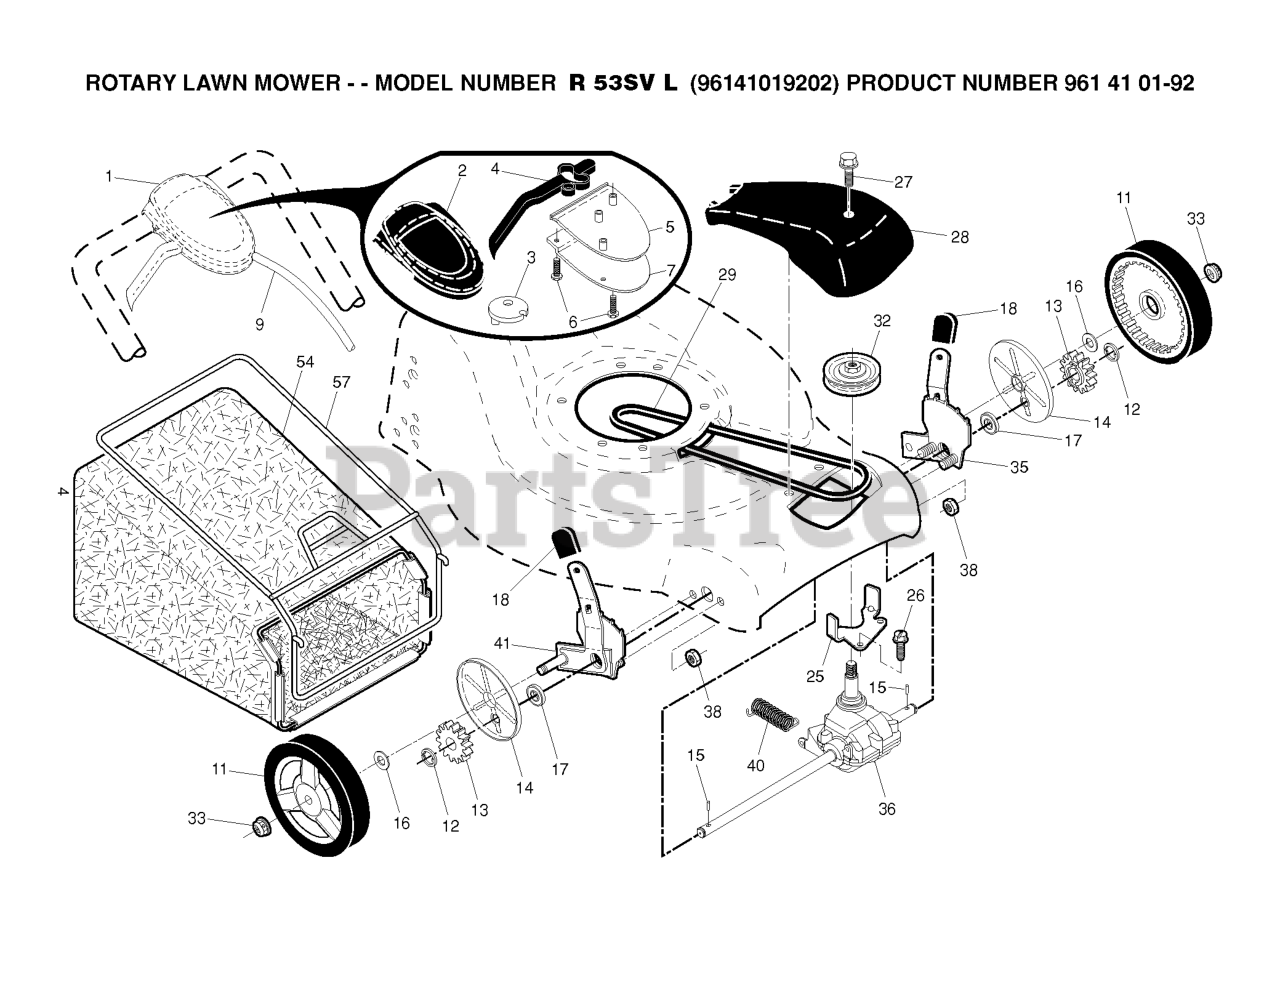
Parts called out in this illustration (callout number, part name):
1	CONTROL.DR.QW.21FGD.BS.GY/BLK
2	COVER TOP AUTO WALK CONTROL
3	PULLEY.CAM.DRIVE.CONTROL.EZ
4	LEVER
5	COVER BOTTOM AUTO WLK CONTROL
6	SCREW, PHILLIPS HEAD 10 X 5/8
7	BRACKET.DRIVE.CONTROL.MOUNT.BL
9	CABLE ASSEMBLY, DRIVE
11	WHEEL.8X1.75.H3SPK.RAD3.GY.BU3
12	E-RING 7/16 RE
13	PINION.14.TEETH.FGD
14	COVER.DUST.WHEEL
15	PAWL, DRIVE
16	WASHER FLUT
17	BEARING
18	SELECTOR KNOB
25	BELT KEEPER
27	SCREW, HEX HD TAPPING #10-24 1
28	COVER.DRIVE.21.FWGD.GRAY
29	BELT.DRIVE.FG
32	RP PULLEY.DRIVE.EZ
33	NUT.HEX.FLANGE.3/8-16.LO(3 2)
35	RP KIT, WHEEL ADJUSTER, LH
36	TRANSMISSION.21.FGD.HT.VST
38	LOCKNUT.NYLOC.1/4-20
41	KIT, WHEEL ADJUSTER, RH
54	Grassbag Assembly
57	FRAME.GBAG.21.FWGD
